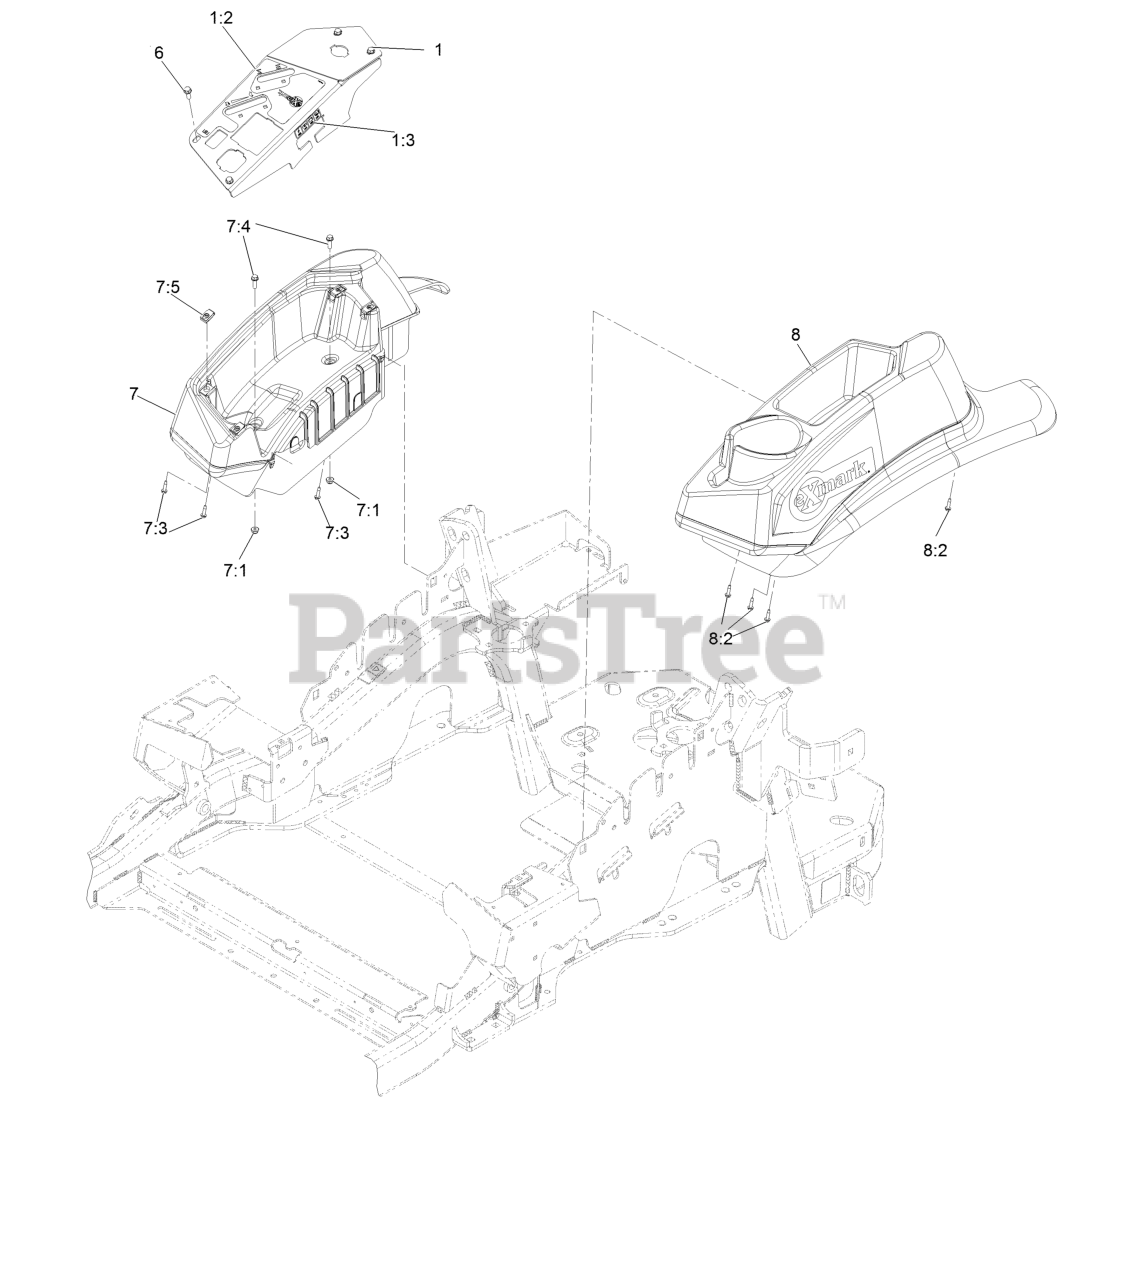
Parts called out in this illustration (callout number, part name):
1	ASM-Panel, Control W/Decal
1:2	Decal-Control Panel Non-Efi
1:3	Decal-Fuses
6	Screw-Machine 1/4-20 X 3/4
7	Console,RH Narrow ASM
7:1	Nut-Nyloc 1/4-20 Flg
7:3	Screw-HWH #10-14 X 3/4 Tf
7:4	Screw-Machine 1/4-20 X 3/4
7:5	Nut-Retainer-Panel 1/4-20
8	Console.LH Narrow ASM
8:2	Screw-HWH #10-14 X 3/4 Tf
